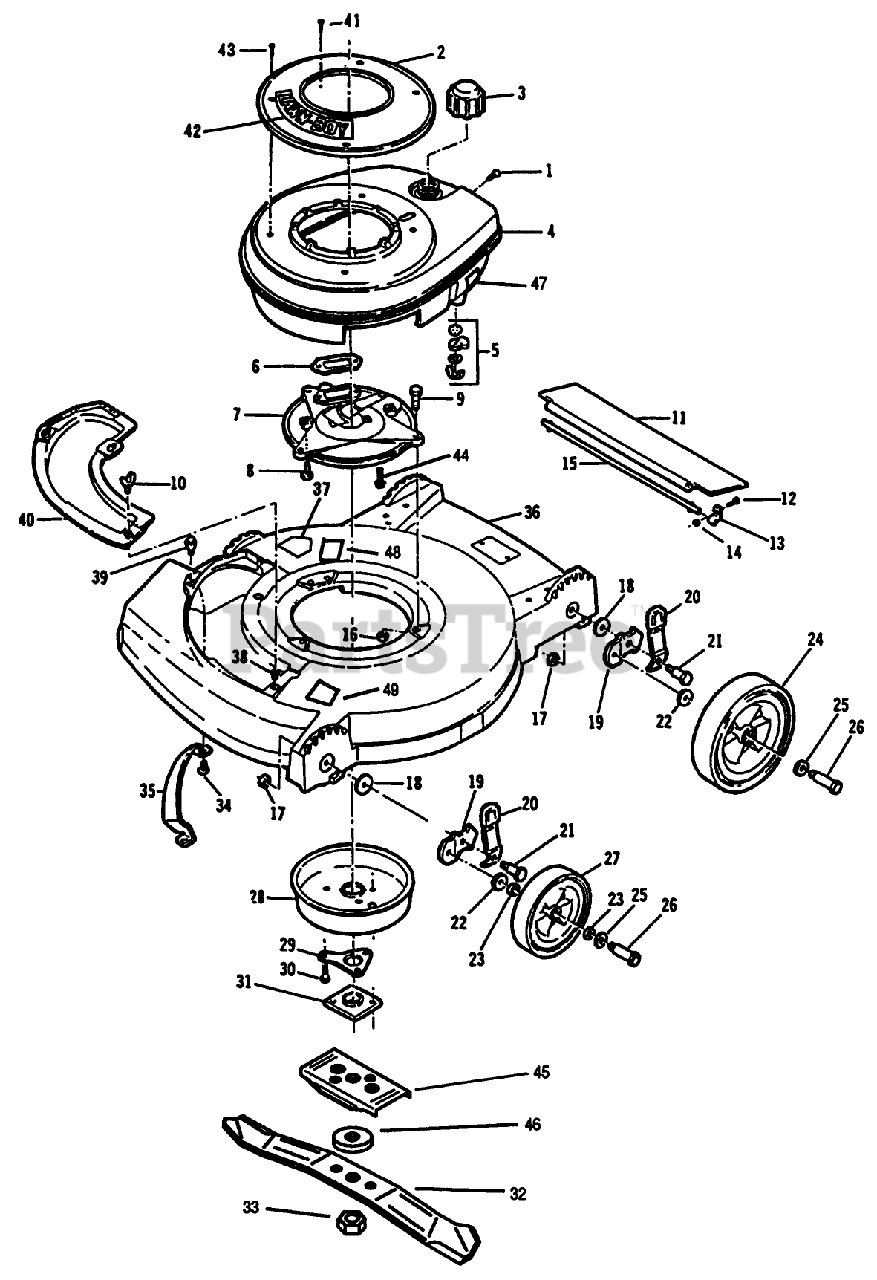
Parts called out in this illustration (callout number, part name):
1	SCREW S
2	STARTER BASE&NUT*B
3	FUEL CAP & INSERT
5	SHUT OFF VALVE KIT
7	PLATE F
8	SCREW V
9	SCREW-HH
10	WING SCREW LAWRE
13	CLAMP ROD KMC
14	LOCKNUT E
15	ROD T/SHIELD ADV WIRE
16	NUT-LOCK F
17	LOCKNUT
18	WASHER
20	SPRING ARM ASM
21	BOLT
22	WASHER WROUGHT
23	WASHER
25	SPACER
26	BOLT WHEEL
28	MUFFLER COVER F
29	SUPPORT F
30	SCREW
31	PLATE AND COLLAR ASM
33	NUT-BLADE
35	TOE BAR 19"
41	SCREW SEMS SM
43	SCREW - SELF TAPPING
44	SCREW-SEMS F
46	WASHER
